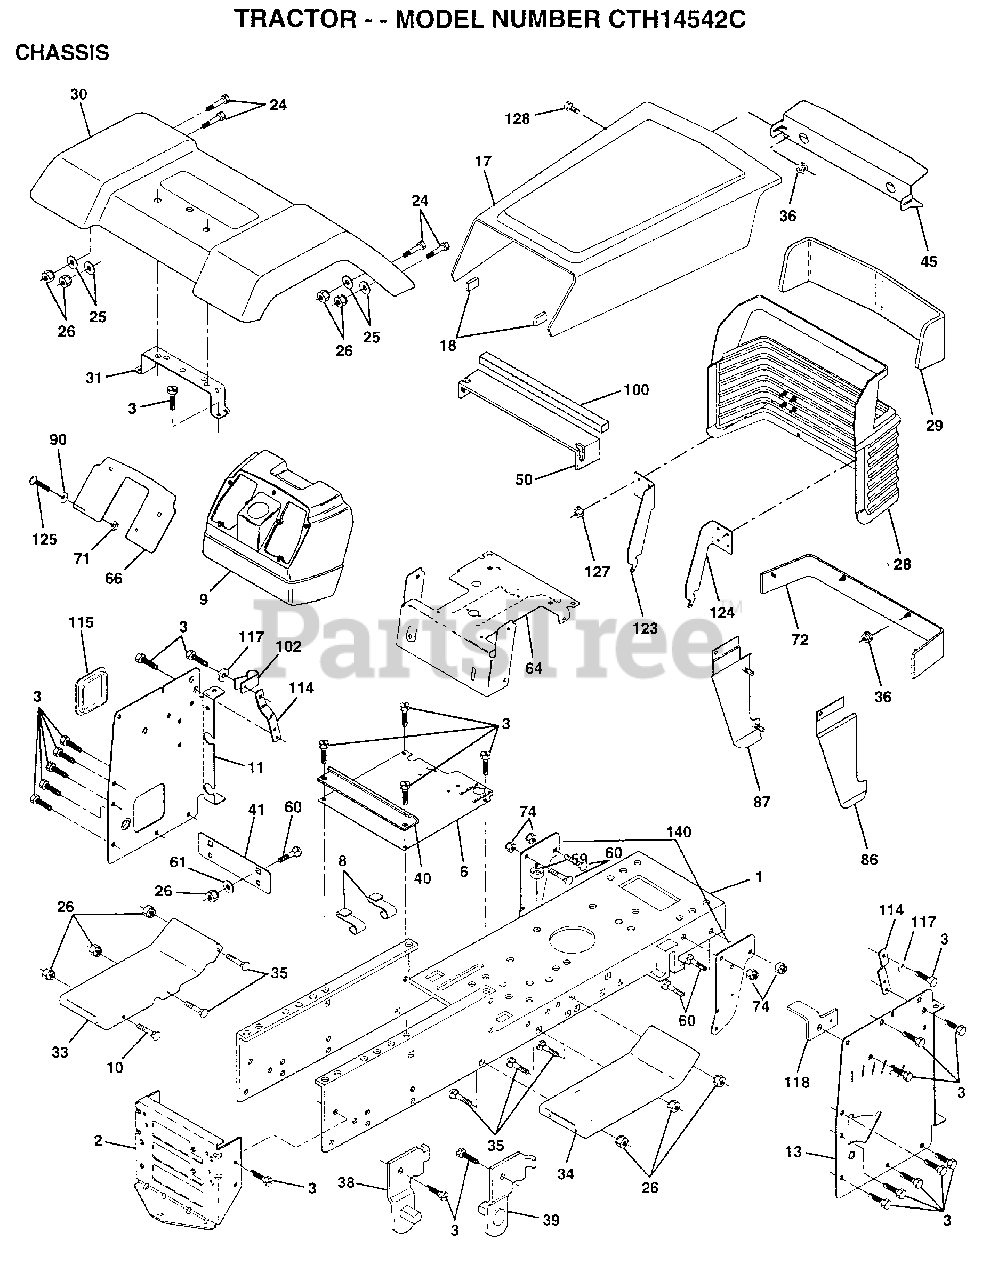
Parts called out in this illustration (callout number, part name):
1	CHASSIS WLDMT 11G
3	SCREW
8	"CLIP,INSULATOR"
9	DASH.PLASTIC.BLK
11	PANEL.DASH.LH.
13	PANEL.DASH.RH.
17	HOOD/GRILLE ASM
24	BOLT
25	WASHER
26	NUT
28	GRILLE ASM WELD
31	BRACKET SUPT FEND
33	FOOTREST.LH.LT/GT
34	FOOTREST.RH.LT/GT
35	BOLT
36	PAL NUT LT
38	BRACKET ASM LH
39	BRACKET ASM RH
40	SPACER FENDER LT
41	PLATE EXTEN FEND
50	"BAFFLE,HOOD"
60	BOLT
61	WASHER
64	DASH.LOWER.LT
66	PLATE DASH SILKSC
71	NUT HXKEP 1/4X20
72	STRAP FENDER ASM
86	PANEL SIDE RH ASM
87	PANEL SIDE LH ASM
90	WASHER PM
100	FOAM STRIP T
102	CLIP T
114	BRACKET.SUPT.DASH
115	COVER ACCESS
117	WASHER.SERRATED.
118	BRACKET.CLUTCH.MC
123	BRACKET.PICK.LH.
124	BRACKET.PICK.RH.
125	SCREW
127	PAL NUT
128	SCREW SPECIAL
